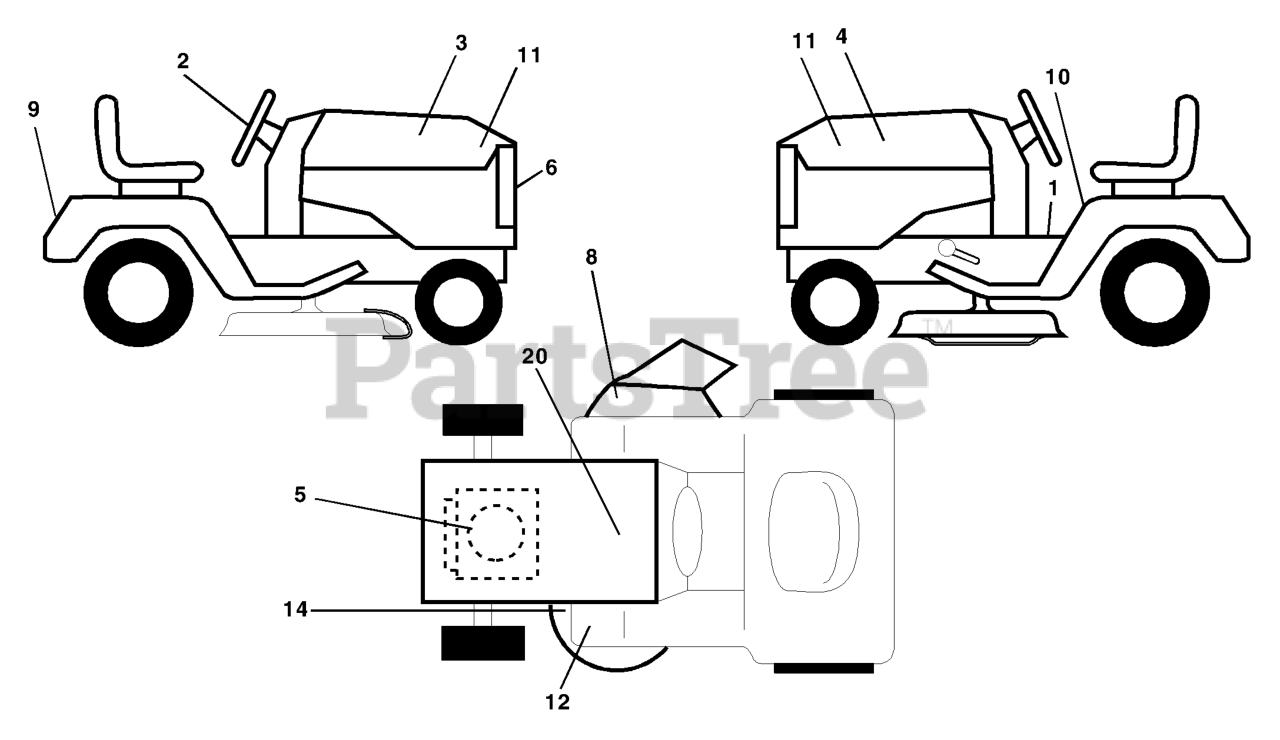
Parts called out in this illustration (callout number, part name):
2	DECAL.WHEEL.STEERING.HUSQ.PERM
3	HOOD DECAL
4	HOOD DECAL
5	DECAL ENGINE
6	DECAL.GRILLE.HUSQ
8	DECAL.WARN.KEEP.HAND.AWAY
9	DECAL, FENDER
10	DECAL FENDER DANGER
11	DECAL HOOD
12	DECAL CLUTCH/BRAKE
14	DECAL V-BELT SCHEMATIC
20	DECAL BTRY SYMBOLS
20	DECAL BY PASS LT HYDRO
